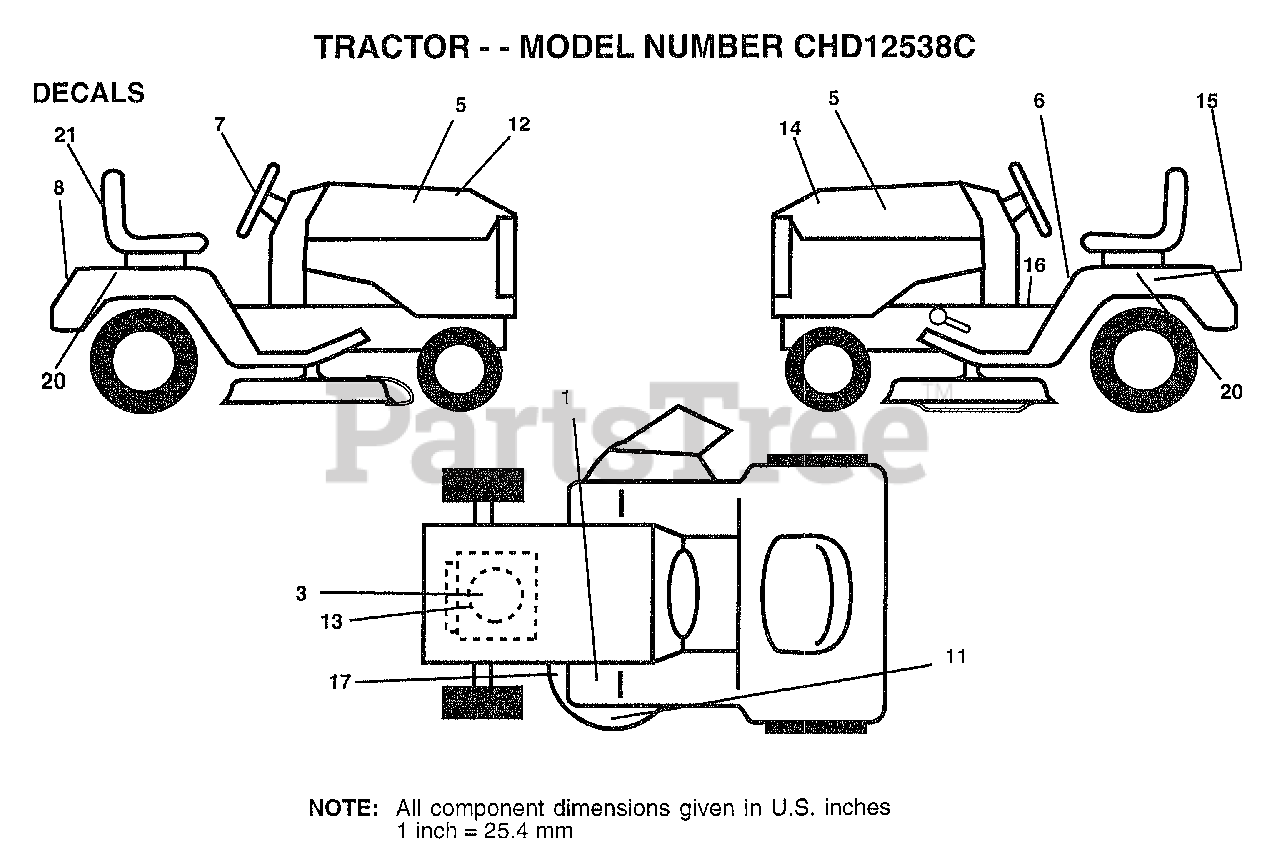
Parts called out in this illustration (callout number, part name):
1	DECAL T
3	DECAL, HP ENGINE
5	DECAL.PANEL.SD.SP
6	DECAL.CAUT.ENG/FR
7	DECAL, INS STRG WH
8	DECAL.FENDER.LOGO
11	DECAL.MOWER.HOME
12	DECAL.HOOD.RH.
13	DECAL.ENGINE.REPL
14	DECAL.HOOD.LH
15	DECAL.BATRY.3-3908
16	"DECAL.OPER,SDL"
17	DECAL
20	DECAL.FEND.SD.5SP
